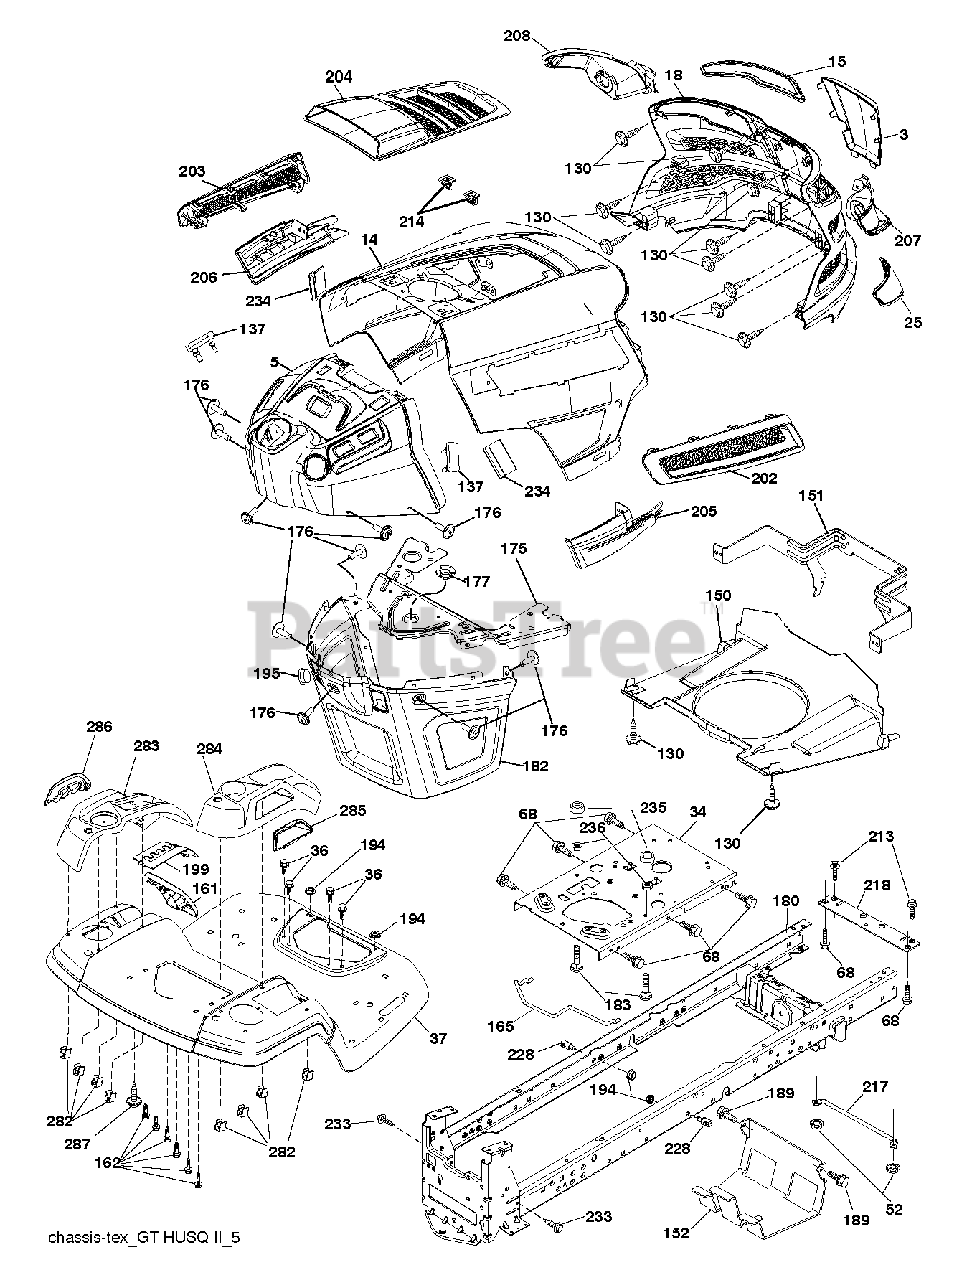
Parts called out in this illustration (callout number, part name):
3	APPLIQUE.SUBASM.GT.HUSQ.II
5	DASH.UPR.ASSY.GT2.SRVMNDER.PTO
14	HOOD.ASM.HUSQVARNA.GT.TEX.422
15	LENS.HEADLIGHT.LH.GTII.2011
18	GRILLE.SUBASM.GT.HUSQ.II
25	LENS.HEADLIGHT.RH.GTII.2011
34	PLATE.ENGINE.WELDED.CHASSIS
36	SCREW 5/16"
37	FENDER.TLT.FS.W/CPH/FW/RSF.ORN
52	LOCKNUT
68	SCREW LT
130	SCREW.#10 X 0.750.BOS
137	BUMPER DASH
150	AIR.DUCT.GTV.BLACK
151	BRACKET.PIVOT.HOOD.GT.HUSQ.II
152	SHIELD.BROWNING.W/TEX
161	WINDOW.FUEL.LT.HUSQ.TEX.498
162	SCREW.HI-LO.CONSOLE
165	SUPPORT.TANK.REAR.W/TEX
175	PLATE.CROSSMEMBER.HUSQ
176	SCREW.#10-24X5/8.RN.QU
177	BUSHING, STEERING
180	CHASSIS
182	DASH.LOWER.COMMON.12V.ADAPTOR
183	BOLT.5/16-18X1-1/4 FULL THD
189	SCREW
191	INSERT.REFLECTIVE.RH.HUSQ.GTII
194	NUT LOCK HEX FLANGE 5/16-18
195	PLUG.HOLE.DASH.LOWER.12V.BLK
199	PLATE.DECK.LIFT.HUSQ.LT
202	VENT.SIDE.RH.GT.HUSQ.II.
203	VENT.SIDE.LH.GT.HUSQ.II.498
204	VENT.TOP.HUSQ.GT2
205	SIDE.TRIM.RH.GT.HUSQ.II
206	SIDE.TRIM.LH.GT.HUSQ.II.GRAY
207	BEZEL LIGHT.RH.GT.II.MYLAR
208	BEZEL LIGHT.LH.GT.II.MYLAR
213	BOLT
214	CLIP.RETAINER.TINNER.
217	ROD.PIVOT.HOOD
218	X-PIECE.HOOD.STOP.NON/
228	STUD.FASTNER.W/ANTI-ROTATE
233	BOLT.SHOULDER
234	BUMPER.HOOD.TEX.HUSQVARNA
235	SPACER FENDER
236	NUT.CENTERLOCK.5/16-
282	CLIP.RETAINER.CONSOLE.LT.HUSQ
283	CONSOLE.DECK.LIFT.R.SDFL.HUSQ
284	CONCOLE.CNTRL.PDL.HUSQ.LT.498
285	CONSOLE INSERT RH
286	CONSOLE.INSRT.LH.HUSQ.LT.BLACK
287	SCREW 1/4X20
297	INSERT.REFLECTIVE.LH.HUSQ.GTII
